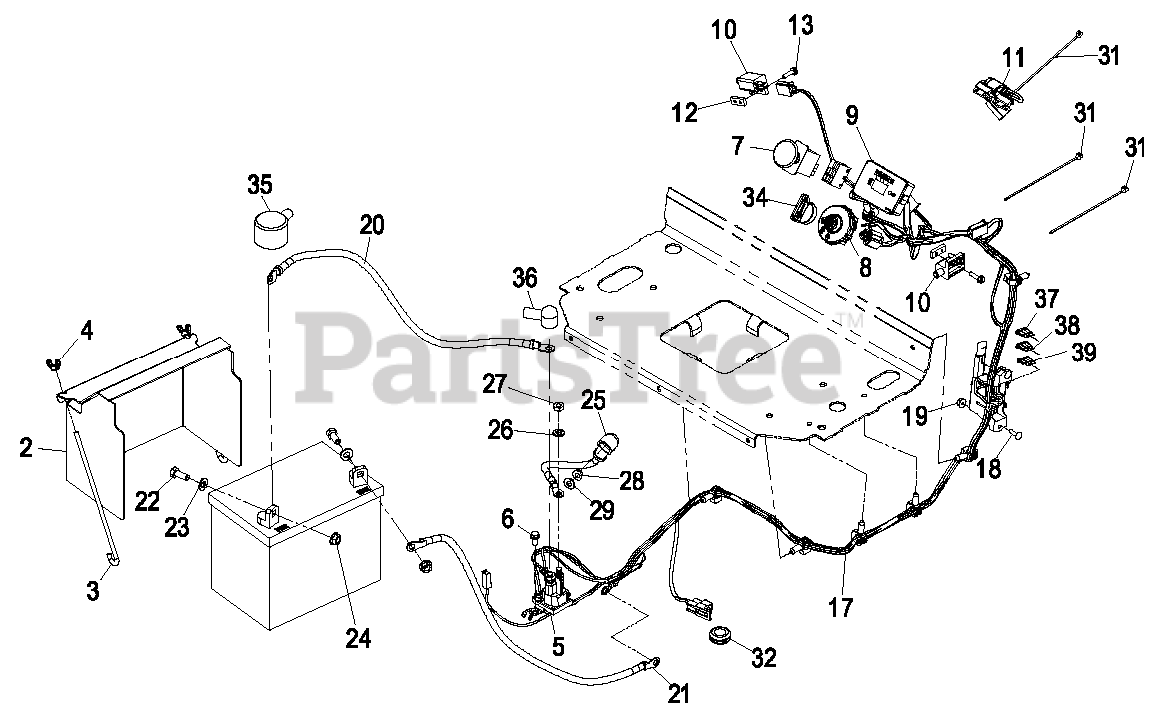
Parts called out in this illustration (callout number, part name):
2	COVER-BATTERY
3	BOLT-HOLDDOWN
4	WINGNUT
5	SOLENOID
6	SCREW-HWH
7	SWITCH-PTO, ON-ON
10	SWITCH-CLOSED, NORMALLY
11	HARNESS-SWITCH, REED
12	PLATE-TAPPED
13	SCREW-HWH
17	HARNESS-WIRING
18	BOLT-CARR
20	POSITIVE BATTERY CABLE AS
21	CABLE-BATTERY, BLACK
22	SCREW-HH
23	WASHER-PLAIN
24	NUT-HHF, SMOOTH
25	CABLE-BATTERY, RED
26	WASHER-LOCK
27	NUT-JAM
29	WASHER-FLAT
31	TIE-CABLE
32	GROMMET
34	KEY-IGNITION
35	INSULATOR-BATTERY
36	INSULATOR-SOLENOID
37	FUSE-BLADE, 10 AMP
38	FUSE-BLADE, 25 AMP
39	FUSE-BLADE, 30 AMP
